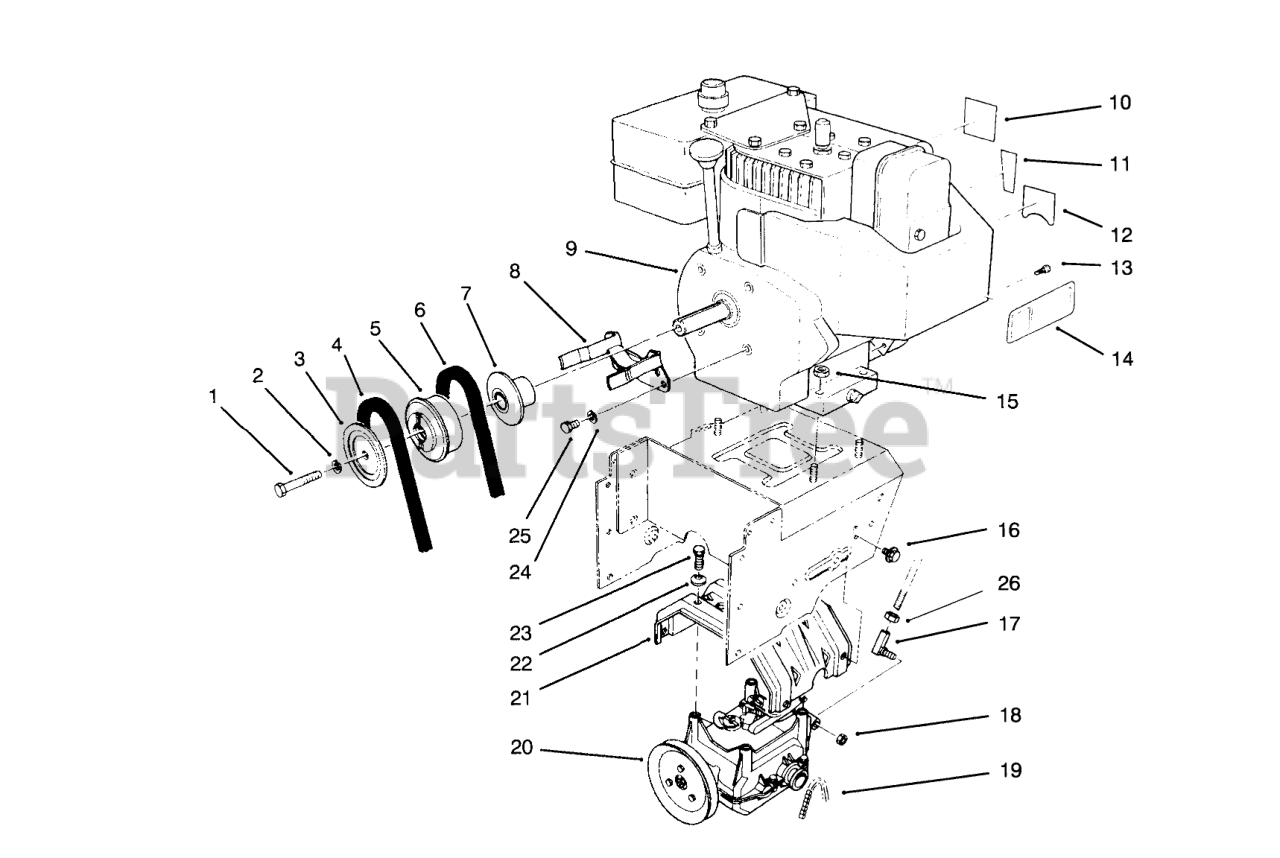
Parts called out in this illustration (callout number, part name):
1	SCREW-HH
2	WASHER-LOCK
3	SHEAVE-HALF, IMPELLER
4	V-BELT
5	LH CASTOR ARM ASM
6	V-BELT-TRACTION
7	SHEAVE-HALF, TRACTION
8	Guide-Belt
9	Engine
10	DECAL-PRIMER
11	DECAL-THROTTLE
12	DECAL-CHOKE
13	SCREW-HWH
14	DECAL-WARNING, HOT SURFACE
15	NUT-HF
16	SCREW-HHF
17	JOINT-BALL
18	NUT-LOCK, NI
19	CHAIN
20	TRACTION GEARCASE ASM
21	Frame-Transmission
22	WASHER-SPRING
23	SCREW-HWHTF
24	WASHER-LOCK
25	SCREW-HH
26	NUT-HJ
